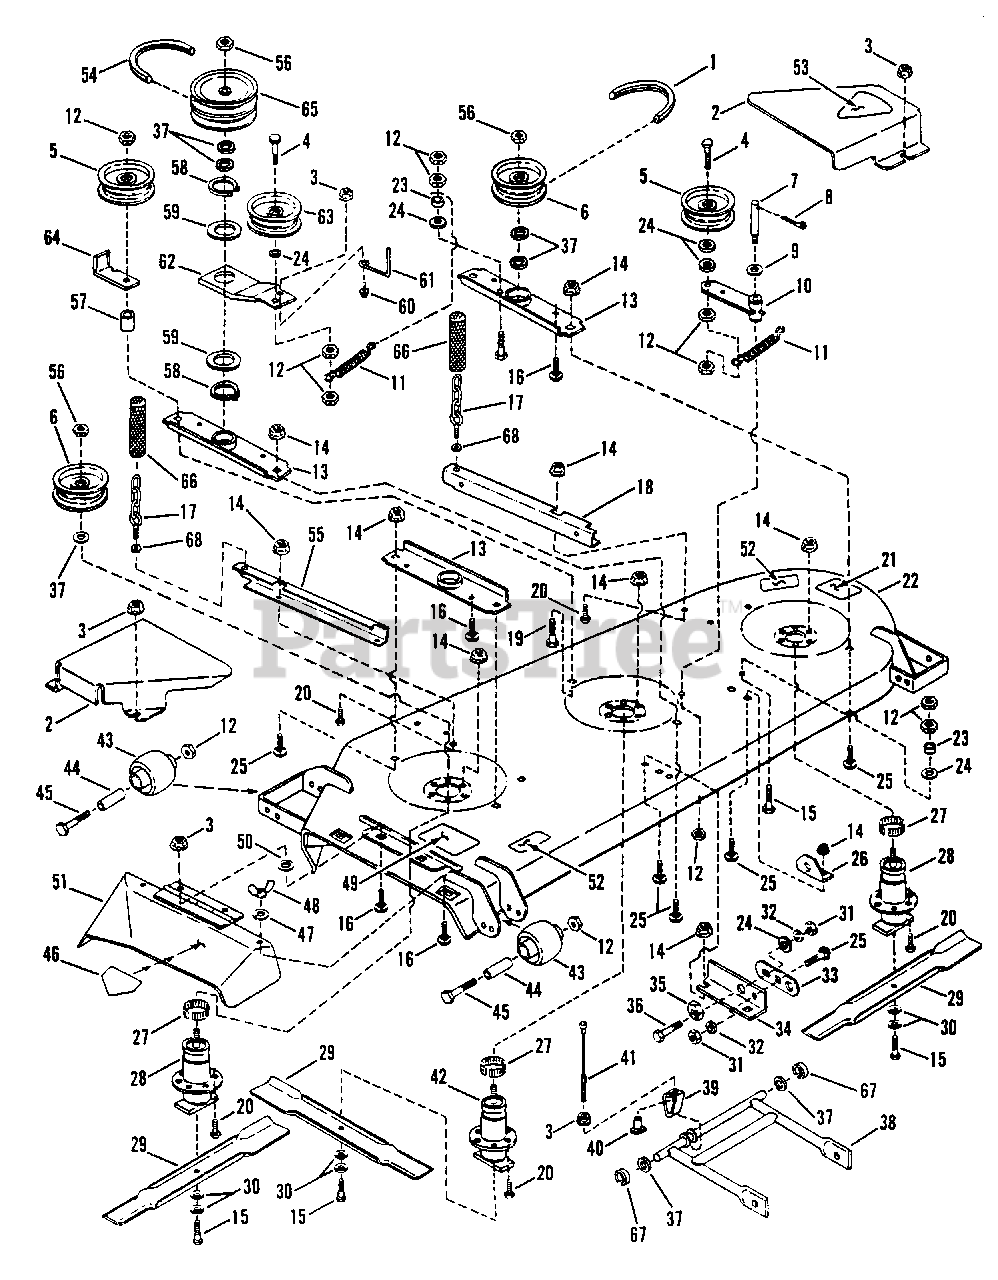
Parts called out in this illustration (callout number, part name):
1	V-BELT, 48" Cutting Deck
2	GUARD, Pulley
3	NUT, 5/16-18 Hex Fl. Lk., Gr. 5
4	SCREW, 3/8-24 x 2" H.H.C., Gr. 5
5	PULLEY, Idler, V, 4-1/2" O.D.
6	PULLEY, Idler, Flat, 4-3/4" O.D.
7	STUD, Idler
8	COTTER-PIN, 1/8 x 1"
9	WASHER, 5/8 SAE Flat
10	ASSEMBLY, Idler Arm
11	SPRING
12	NUT, 3/8-24 Hex Lock
13	BRACE, Spindle
14	NUT, 3/8-16 Hex Flange Lock
15	SCREW, 3/8-24 x 1-1/4" Gr. 5
16	BOLT, 5/16-18 x 5/8 Carr. Gr. 5
17	ASSEMBLY, Adj. Bolt-Chain
18	ASSEMBLY, Support RR Left
19	SCREW, 3/8-24 x 2-1/2" H.H.C., Gr.5
20	BOLT, 3/8-16 x 3/4" Flange Lock
21	DECAL-CAUTION
22	DECK, 48" Cutter
23	SPACER
24	WASHER, 3/8 SAE
25	BOLT, 3/8-16 x 3/4" S.N.C., Gr.2
26	BRACKET, Front Hanger (Left Side)
27	RING, Tolerance, 3/4"
28	ASSEMBLY, Spindle
29	BLADE, 16.5"
30	WASHER, Cone
31	NUT, 3/8-16 Hex, Gr. 5
32	WASHER, 3/8 Split Lock
33	LINK, Adjustment
34	BRACKET, Front Hanger (Right Side)
35	RING, Adjustment
36	SCREW, 3/8-16 x 1" H.H.C., Gr. 5
37	WASHER, 3/4 I.D.
38	ARM, Front Lift
39	BRACKET, Front Lift Arm
40	T-NUT, 5/16-18
41	CABLE, Front Lift
42	ASSEMBLY, Spindle
43	WHEEL, Gage, Front
44	SPACER
45	SCREW, 3/8-24 x 3-3/4", Gr. 5
46	DECAL-DANGER
47	WASHER, 5/16 Split Lock
48	WING-NUT, 5/16-18
49	DECAL- CAUTION, Deflector in Place
50	RETAINER, 5/16 Bolt
51	ASSEMBLY, Side Chute
52	FOOTPAD
53	DECAL - 48 Inch
54	V-BELT, Drive, A92
55	ASSEMBLY, Support RR Right
56	NUT, 3/4-16 Hex Jam Lock
58	RING, 2" External Retaining
59	WASHER, Plastic
60	BOLT, 5/16-18 x 3/4" S.N.C., Gr. 5
61	GUIDE, Belt
62	ARM, Idler, Center
63	PULLEY, Idler, Flat, 4.8" O.D.
64	GUIDE, Belt
65	PULLEY, Double, 5" O.D. & 4-3/4" 0.D.
66	COVER, Chain
67	RING
68	NUT, 3/8-16 Hex Jam
